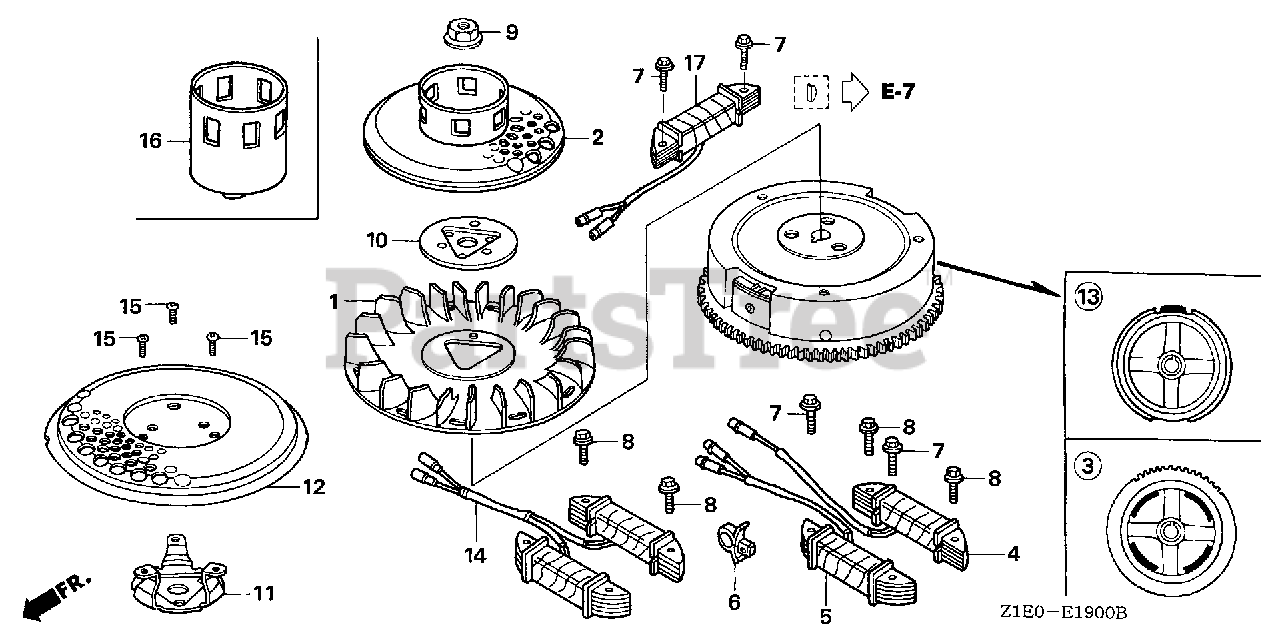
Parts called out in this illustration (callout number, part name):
1	FAN, COOLING
2	PULLEY, STARTER (SCREEN GRID)
3	FLYWHEEL COMP. (SEL-4 POLE)
5	COIL ASSY., CHARGE
6	CLIP, BRAKE PIPE (A) (FOR NEUTRAL SWITCH)
7	BOLT, FLANGE (6X28) (CT200) Use up to Engine SN 1530314.
9	NUT, SPECIAL (16MM) (1)
